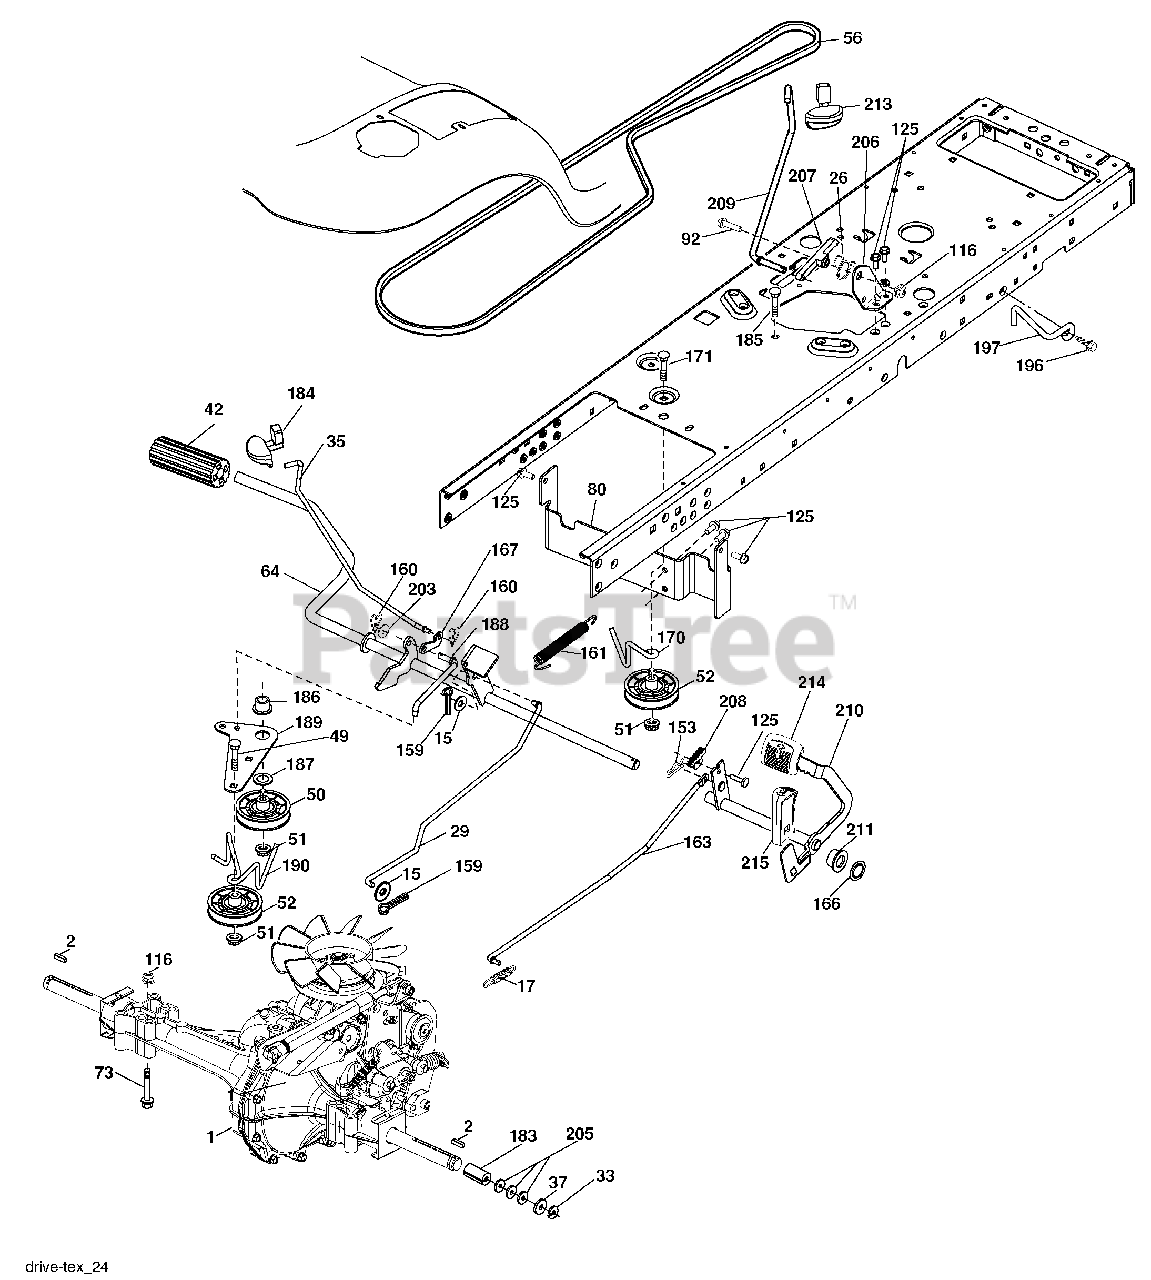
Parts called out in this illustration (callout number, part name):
2	Key
15	Washer 13/32 x 13/16 x 16 Ga.
17	Spring, Brake
26	Spring Return Cruise
29	Rod, Brake
33	Ring E
35	Rod, Brake, Park
37	Washer 25/32 x 1-1/4 x 16 Ga.
42	Cover, Foot Pedal
49	Bolt
50	Pulley Idler Flat
51	Lock Nut 3/8-16
52	Idler V-Groove 910" Offset
56	V-Belt, Drive
64	Shaft Asm. Pedal Brake Control
73	Bolt Hex Flghd 5/16-18 Gr. 5
80	Bracket Strap Torque
92	Bolt Fin Hex 5/16-18 unc x 1.25
116	Nut Lock Hex Flange 5/16-18
125	Screw 5/16-18 x 3/4
153	Retainer Spring
159	Pin Cotter 1/8 x 3/4
160	Retainer Clip
161	Spring, Return, Clutch
163	Rod Pedal Control
166	Nut Push .625
167	Latch Brake Parking
170	Keeper Belt Centerspan
171	Bolt
183	Spacer Axle
184	Handle Parking Brake
185	Bolt
186	Spacer Retainer
187	Washer
188	Link Clutch Ground Drive
189	Bellcrank Ground Drive
190	Keeper Bellcrank Ground Drive
196	Screw 3/8-16 x 1
197	Link Clutch Anti Rotation
203	Washer 11/32 x 11/16 x 16 Ga.
205	Washer 25/32 x 1-5/8 x 16 Ga.
206	Bracket Mount Latch Cruise
207	Latch Control Cruise
208	Gear Sector Control Cruise
209	Rod Control Cruise
210	Rockr Asm. Pdeal Control
211	Bearing Nylon
213	Knob control Cruise
214	Pad Pedal Forward
215	Pad Pedal Reverse
